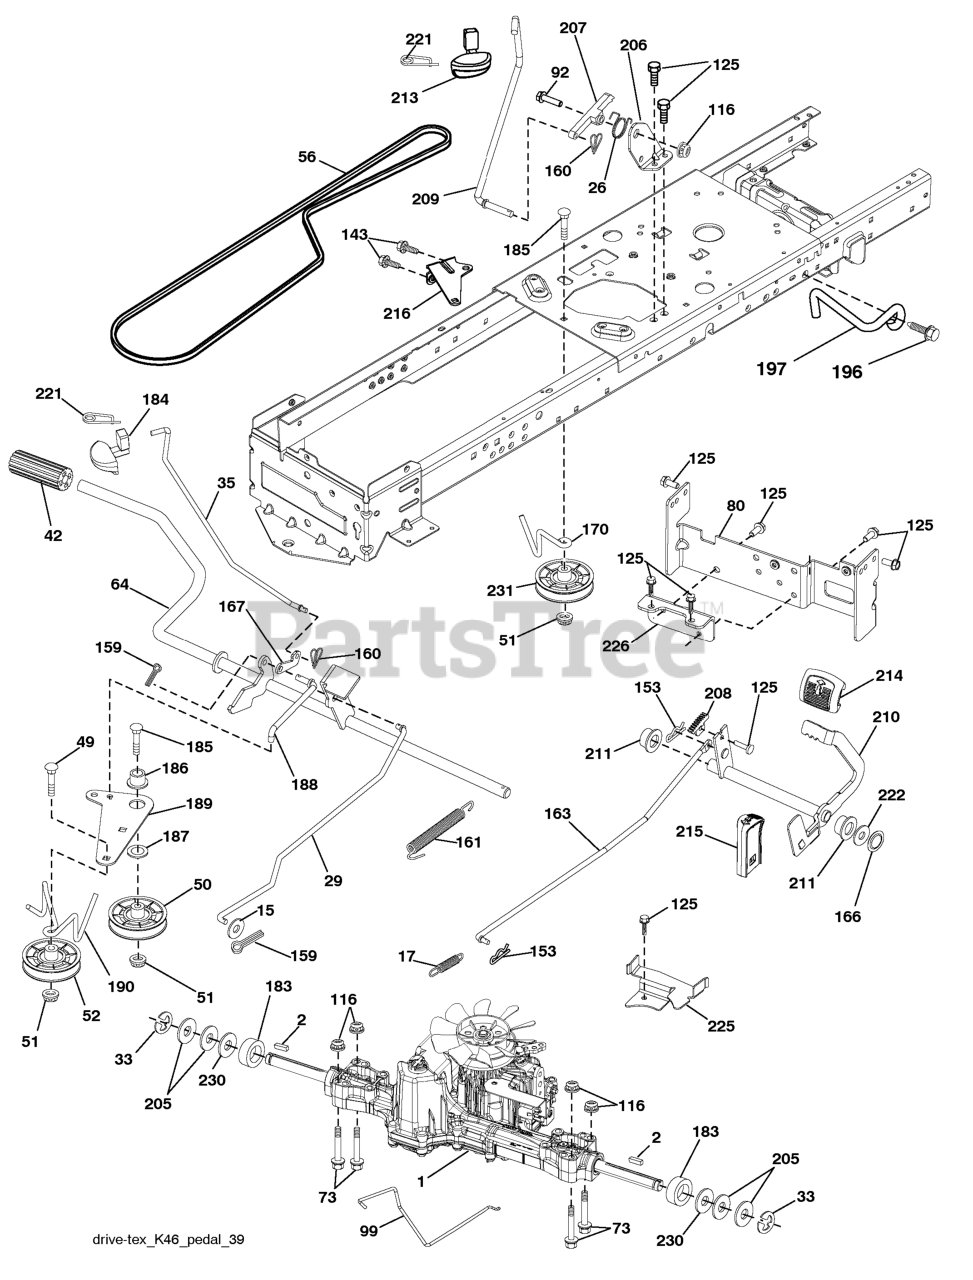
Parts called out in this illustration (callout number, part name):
2	SQUARE KEY
15	WASHER
17	SPRING.BRAKE.K46.GREEN
26	SPRING.RETURN.CRUISE
29	ROD.BRAKE.K46
35	ROD.BRAKE.PARKING.GT.H
42	PEDAL COVER T
50	IDLER.FLAT.910.OFFSET
51	NUT LOCK FLG 3/8-16 UNC
52	IDLER.V-GROOVE.910.OFFSET
56	V-BELT.MOWER.92.40.42/K46
64	SHAFT.ASM.PEDAL.BRK.CNTR
73	BOLT HEX 5/16-18 GR 5
80	STRAP TORQUE
92	BOLT
99	ROD.SPRING.BYPASS.K46.LT.Z
116	NUT LOCK HEX FLANGE 5/16-18
125	SCREW
143	Screw Thdrol 5/16-18 x 1/2
153	RETAINER M
159	COTTER PIN
160	RETAINER CLIP
161	SPRING, RETURN LT
163	ROD.CONTROL.PEDAL.K46
166	NUT.PUSH.625
167	LATCH.BRAKE.SPRING
170	KEEPER.CENTER SPAN.1.688
183	SPACER AXLE
184	HANDLE.PARKG.BRK.HUSQ X667
186	SPACER.RETAINER
187	WASHER 12/32X2X10GA
188	RP.LINK.CLUTCH.GROUND.DRIVE
189	BELLCRANK.GROUND.DRIVE.TEX.
190	KEEPER.BELLCRANK.DRIVE
196	SCREW 3/8-16X1
197	LINK.CLUTCH.ANIT-ROTAT
206	BRKT.MOUNT.LATCH.CRUIS
207	LATCH.CONTROL.CRUISE
208	GEAR.SECTOR.CONTROL.CR
209	ROD.CONTROL.CRUISE.GT.
210	ROCKER.ASM.PEDAL.CONTR
211	BEARING.NYLON
213	KNOB.CONTROL.CRUSIE.HU
214	PEDAL.FORWARD.PAD.TEX
215	PEDAL.REVERSE.TEX.GT.4
216	BRACKET.PULLEY.IDLER.W/TEX
221	RETAINER.SPRING.CLIP.H
222	WASHER 21/32 X 1-1/4 X 10 GA.
225	KEEPER.BELT.TRANSAXLE.K46
226	BRACKET.MOUNT.TORQUE.K46.TLT
230	WASHER.HARDENED
231	IDLER.V-GROOVE.1.688.OFFSET
